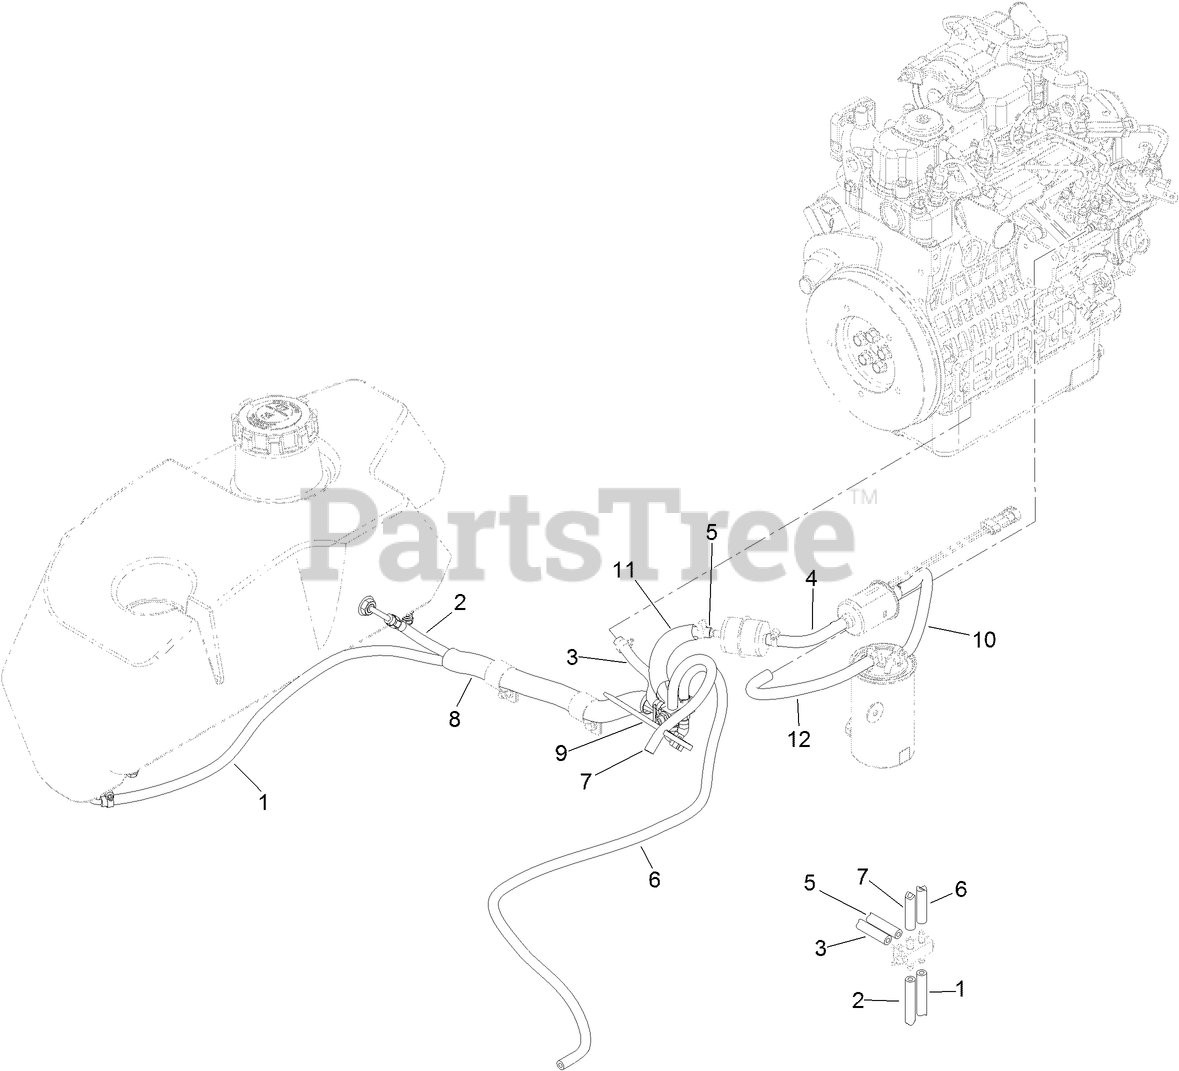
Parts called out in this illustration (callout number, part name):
1	HOSE-FUEL
2	HOSE-FUEL
3	HOSE-FUEL
4	HOSE-FUEL
5	HOSE-FUEL
6	HOSE-FUEL
7	HOSE-FUEL
8	SLEEVE-FABRIC
9	TIE-PLASTIC
10	HOSE-FUEL
11	CONDUIT-FUEL LINE
12	HOSE-FUEL
